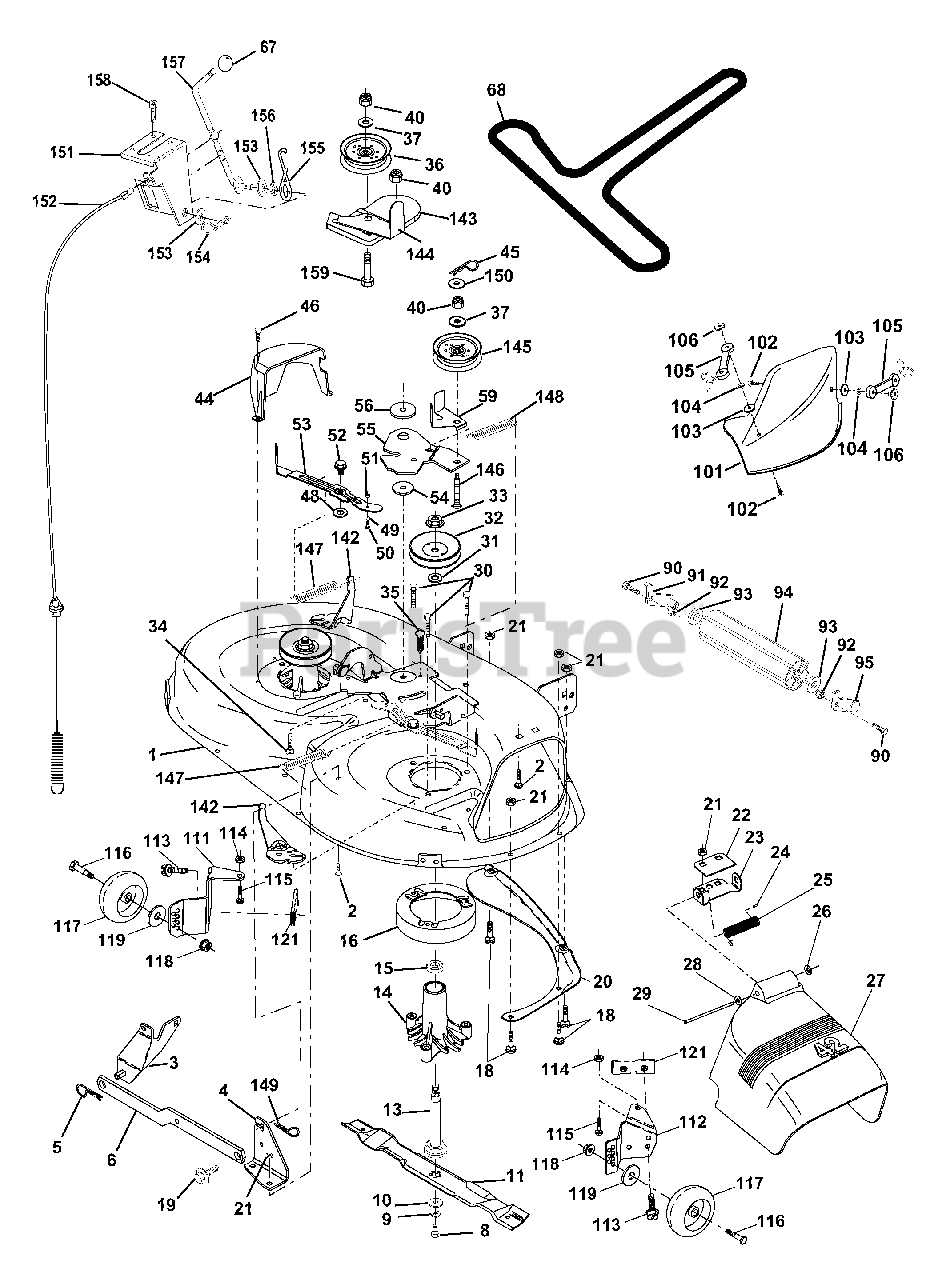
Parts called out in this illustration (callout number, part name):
1	Mower Deck Assembly, 42"
2	Bolt
3	Bracket Asm Fr. Sway Bar 3/42
4	Bracket Asm Deck 42" Sway Bar
5	Retainer Spring
6	Arm, Suspension, Rear
8	Bolt 3/8-24 x 25 Grade 8 patched
9	Washer, Lock
10	Washer,Hardened
11	Blade, Mulching 42"
11	Blade Mower 42" Hi-Lift
13	Shaft Assembly, Mandrel, Vented
14	Housing, Mandrel, Vented
15	Bearing, Ball, Mandrel
16	Stripper, Mower Deck
18	Bolt, Carriage 5/16-18 x 5/8
19	Bolt, Shoulder
20	Baffle, Vortex
21	Nut
22	Stiffener Bracket
23	Bracket, Deflector Mower 42"
24	Cap, Sleeve 80 x 112 Blk Mower
25	Spring, Torsion, Deflector 2 52
26	Nut, Push Phos & Oil
27	Shield, Deflector 42" Blk
28	Washer 11/32 x 5/8 x 16 Gauge
29	Rod, Hinge 42" 6 75 W/G
30	Screw Thdrol Washer Head
31	Washer, Spacer Mower Vented
32	Pulley, Mandrel
33	Nut, Toplock 9/16
34	Bolt
35	Fastener, Christmas Tree
36	Pulley, Idler, Flat
37	Washer 13/32 x 13/16 x 16 Gauge
40	Nut
44	Guard, Mandrel, LH
45	Retainer
46	Screw, Thdrol 1/4-20 x 5/8 T
48	Washer,Hardened
49	Roller Assembly, Cam Follower
50	Bolt, Shoulder #10-24 Grade 5
51	Locknut
52	Bolt, Shoulder 5/16-18 UNC
53	Arm Assembly, Pad, Brake
54	Washer,Hardened
55	Arm, Idler
56	Spacer, Retainer
59	Guard TUV Idler
67	Knob
68	V-Belt, 42" Mower
90	Bolt Fin Hex 3/8-16 Unc x 1
91	Bracket Asm. Noseroller LH
92	Nut, Lock, Hex W/Ins 3/8-16 UNC
93	Washer 17/32 x 7/8 x 16 Ga.
94	Roller, Nose
95	Bracket Asm. Noseroller RH
101	Mulcher Cover
102	Screw, Pan Hd Phillip 10-24 x 5/8
103	Washer, Flat
104	Washer, Lock
105	Latch Assembly
106	Nut, Weld
111	Bracket, Gauge, Wheel LH
112	Bracket, Gauge, Wheel RH
113	Screw 5/16-18
114	Nut, Keps 5/16-18 UNC
115	Bolt, Carriage 5/16-18 x 1/2
116	Bolt, Shoulder
117	Wheel, Gauge
118	Nut Centerlock 3/8-16
119	Washer 3/8 x 7/8 x 14 Ga.
121	Bracket, Extruded
142	Arm Spring Brake Mower
143	Bracket Arm Idler 42"
144	Keeper Belt 42" Clutch Cable
145	Pulley Idler Flat
146	Bolt Carriage Idler
147	Spring Extension
148	Spring Return Idler
149	Retainer Spring Yellow
150	Washer 9/32 x 3/4 x 16 Ga.
151	Bracket Clutch Cable
152	Clutch Cable 42"
153	Washer Flat 3/8" Type B
154	Spring Retainer
155	Spring Retention LVR CLTCH CAB
156	Spacer Clutch Cable
157	Rod Clutch Cable 3/8"
158	Screw Hex Thd Cut 1/4-20 x 5/8
159	Bolt Rdhd Sqn 3/8-16 UNC x 1-3/4
